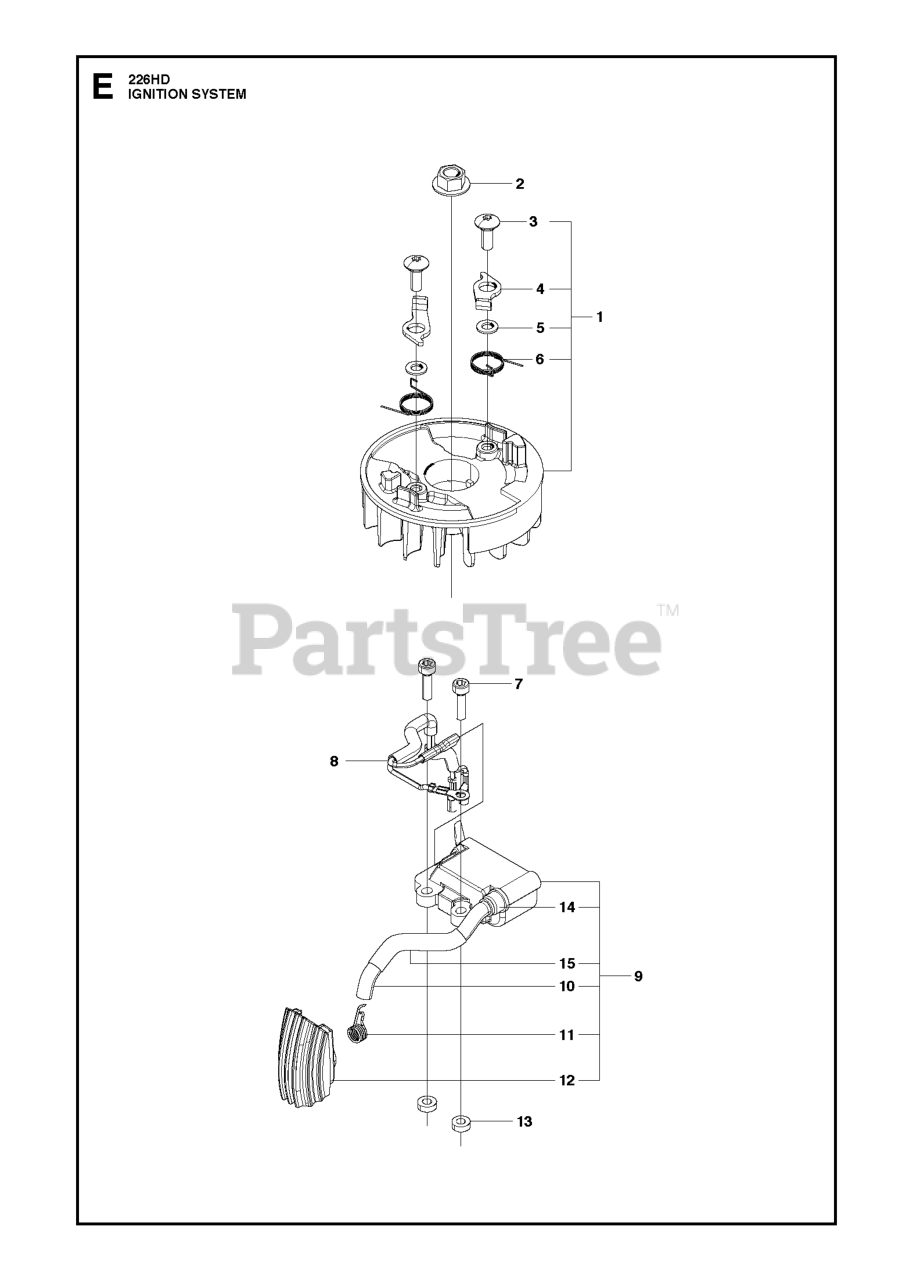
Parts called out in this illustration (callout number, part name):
1	ROTOR ASSY
2	NUT
5	WASHER 5X10X10
14	CAP
